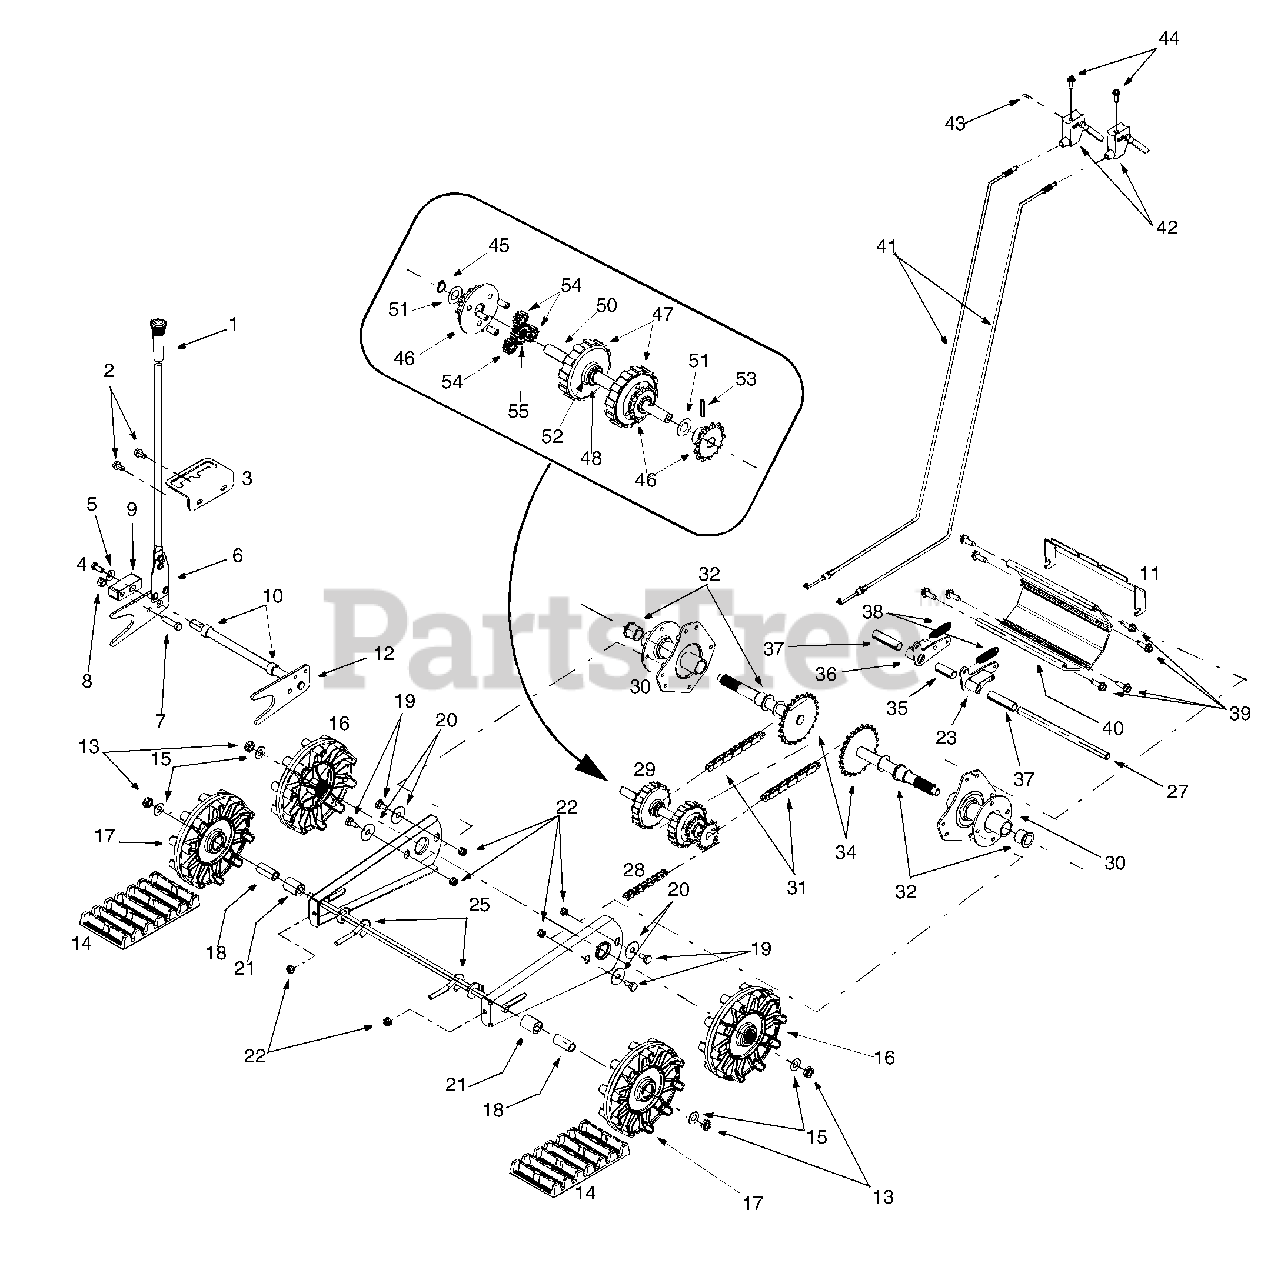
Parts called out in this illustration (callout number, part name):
2	Tap Screw, 5/16-18 x .625
4	Hex Cap Screw, 5/16-24 x .75
5	Bell Washer, .34 ID x .872 OD
7	Hex Cap Screw, 3/8-24 x 1.5
8	Hex Nut, 3/8-24
9	Lift Shaft Drive
10	Spacer, .628 ID x .875 OD x .5
13	Jam Nut, 1/2-20
14	Snow Track
15	Flat Washer, .5 x 1 x .06
16	Track Drive Wheel
17	Track Idler Wheel
18	Spacer, .51 ID x .75 OD x 1.67
19	Shoulder Screw, .435 x .178-5/16 x .56
20	Flat Washer, .442 x 1.38 x .06
21	Spacer, .51 ID x 1 OD x 1.34
22	Hex Nut, 5/16-18
23	LH Dogg Assembly
25	Eye Bolt, 5/16-18 x 3
27	Actuator Shaft
28	Chain
29	Track/Steering Shaft Assembly
31	Chain
32	Flange Bearing
34	Axle Assembly
35	Split Spacer, .514 x .630 x 1.59
36	RH Dogg Assembly
37	Split Spacer, .514 x .630 x 2.44
38	Ext. Spring
39	Tap Screw, 5/16-18 x 1
40	Track Housing
41	Steering Cable
42	Steering Trigger
43	Flange Nut
44	Screw, #10-24 x 1.375
45	Retaining Ring
46	Carrier Assembly
47	Ring Gear
48	Retaining Ring
50	Track Steering Drive Shaft
51	Flat Washer,.58 x 1.06 x .02
52	Flat Washer, 5/8 x 1 x .03
53	Spirol Pin, 3/16 x 1
54	12-Tooth Gear
55	18-Tooth Gear
